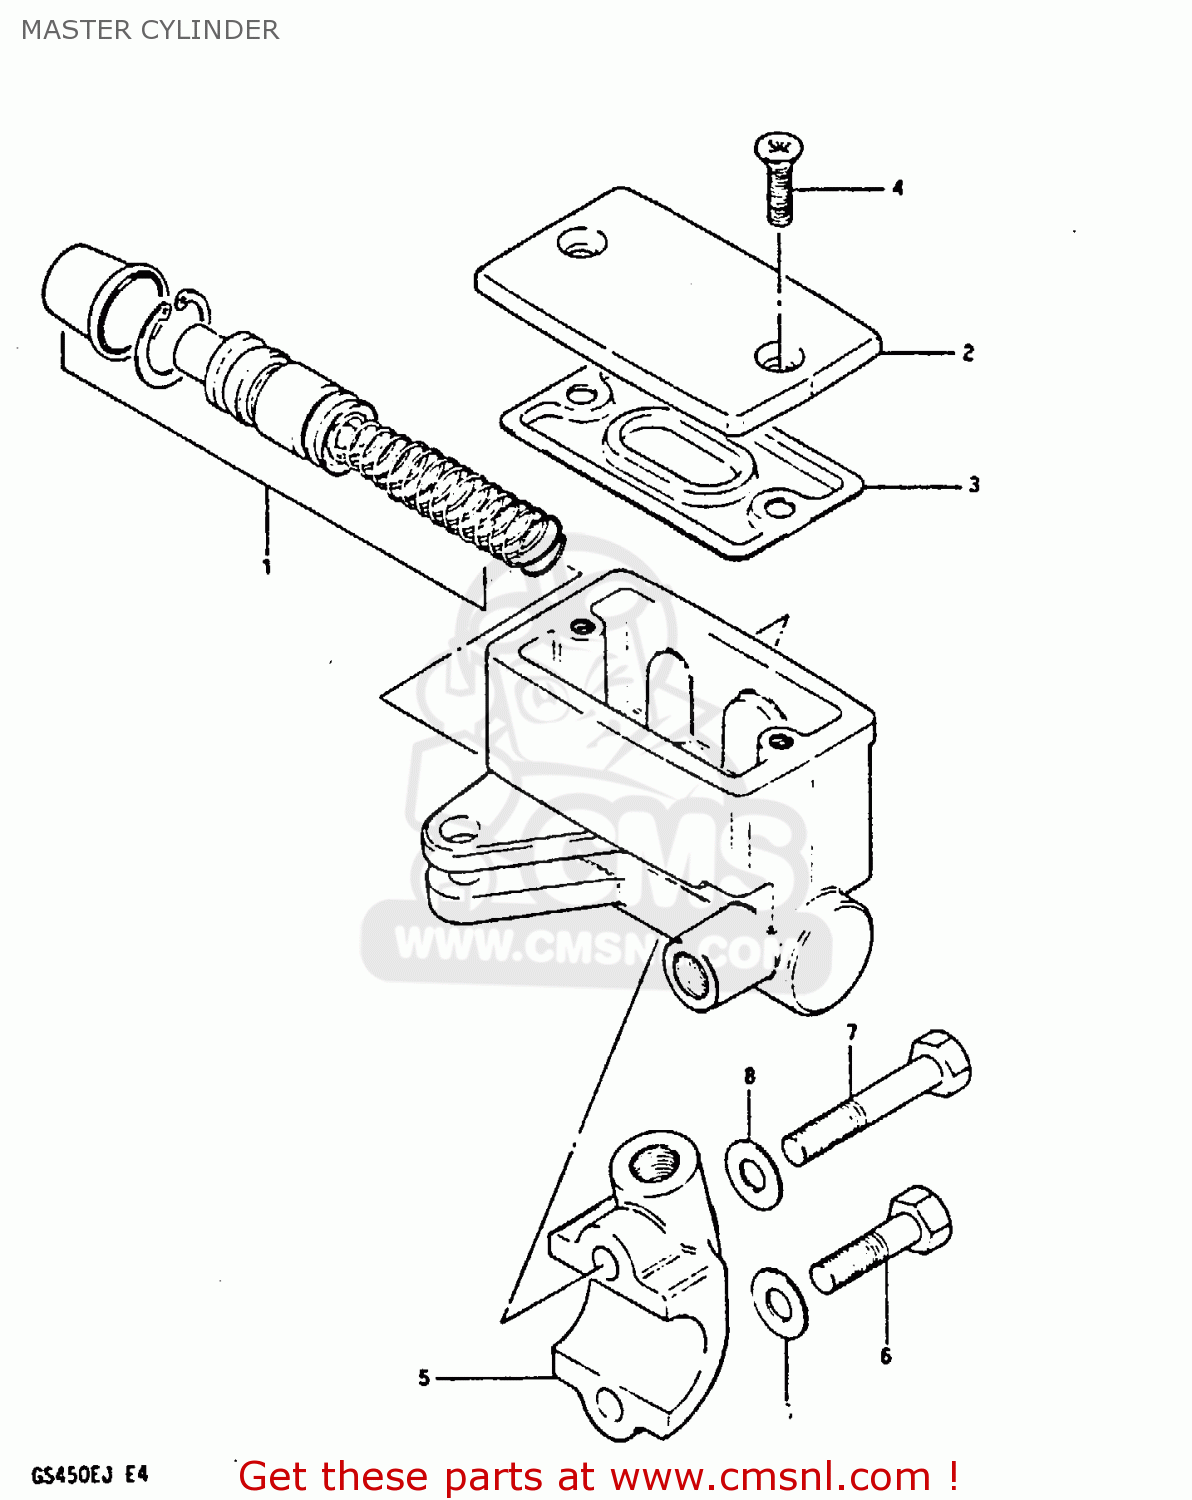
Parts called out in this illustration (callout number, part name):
1	PISTON & CUP SET
2	CAP
3	4
4	SCREW
5	HOLDER
6	BOLT
7	BOLT
8	WASHER
